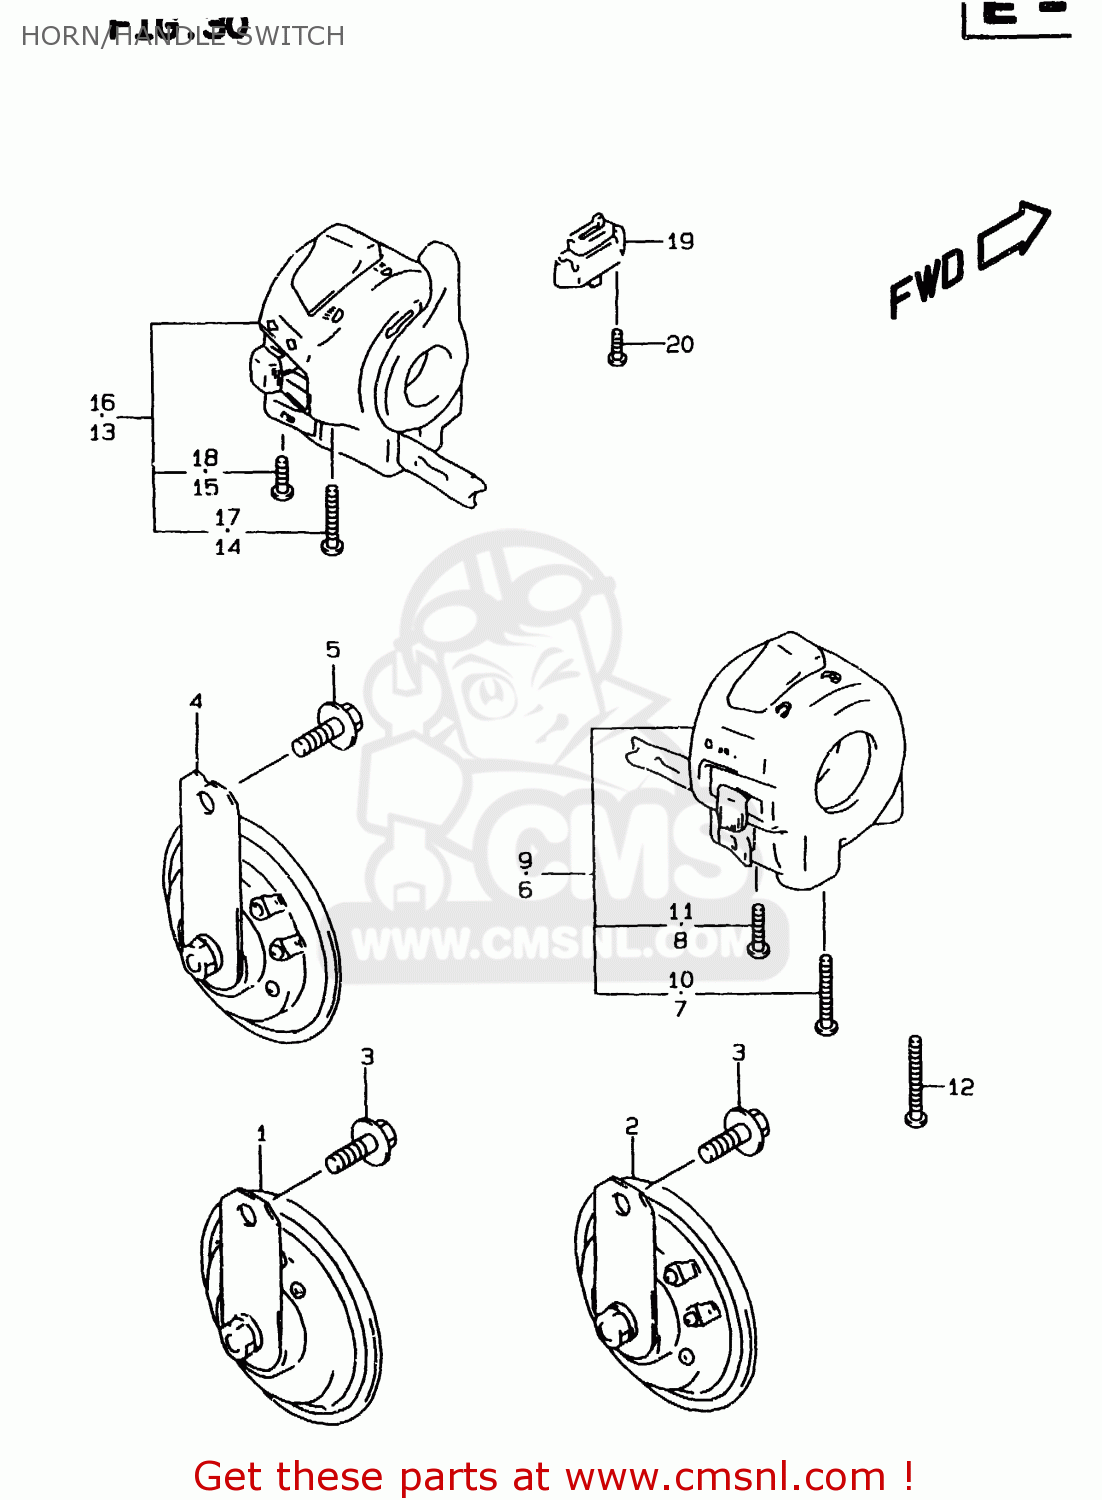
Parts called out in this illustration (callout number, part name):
1	HORN ASSY
2	HORN ASSY,HIGH PITCHED
3	BOLT
4	HORN ASSY
5	BOLT
6	SWITCH,HANDLE,
7	SCREW
8	SCREW
9	SWITCH ASSY,HANDLE,R
10	SCREW
11	SCREW
12	SCREW
13	SWITCH ASSY,HANDLE,L
14	SCREW
15	SCREW
16	SWITCH ASSY,HANDLE,L
17	SCREW
18	SCREW
19	SWITCH ASSY,CLUTCH
20	SCREW
